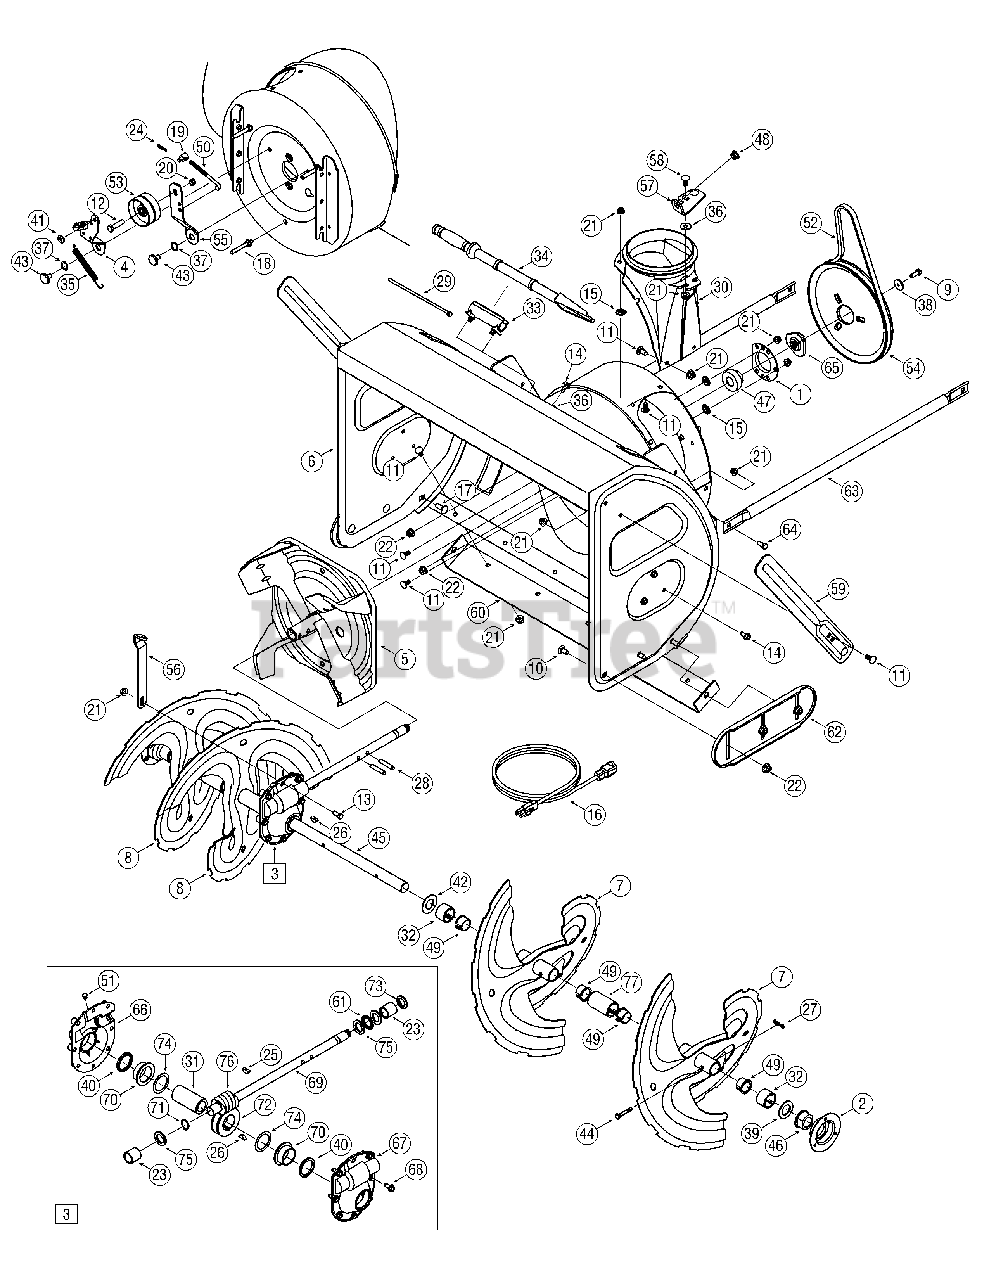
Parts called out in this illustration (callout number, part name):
1	Housing, Bearing
3	Gear Box Assembly, Auger
4	Bracket Assy, Auger Brake
9	Screw, 5/16-24 x .875
10	Bolt, Carriage 3/8-16 x .750
11	Screw, Carriage, 5/16-18 x .75
12	Screw, Hex Cap, 3/8-24 1.5
13	Screw, Hex Cap, 5/16-18 x 1.00
14	Screw, 5/16-18 x .750
15	Nut, Push
16	Extension Cord, 110V
17	Bolt, Carriage 3/8-16 x 1.0
18	Screw, 5/16-18 x .4300
19	Ferrule
20	Nut, Hex Lock, 3/8-24
21	Nut, Flange Lock, 5/16-18
22	Nut, Flange Lock, 3/8-16
23	Sleeve
24	Pin, Internal Cotter
25	Key, Hi Pro, 3/16 x 3/4
26	Key, Woodruff, 1/4 x 3/4
27	Pin, Bowtie Cotter
28	Pin, Spirol, 5/16 x 1.75
29	Tie, Cable
30	Adapter, Chute 6''
31	Shf, Gear Worm
32	Spacer, 1.0 x 1.5 x 1
33	Clip, Mounting
34	Tool, Cleanout
35	Spring, Extension
36	Washer, .349 x .879 x .063
37	Washer, .625 x .885 x.015
38	Washer, Flat, .34 x 1.50 x .150
39	Spacer, 1.004 x 1.375 x.25
40	Oil Seal
41	Washer, .344 x .75 x .12
42	Washer, 1.01 x 1.86 x.06
43	Screw, Shoulder, .625 x .17
44	Pin, Shear, .25 x 1.75
45	Axle, Sprial, 33''
46	Bearing, Flange w/ Flats
47	Bearing, Self Aligning
48	Bushing, Nylon
49	Bushing, Flange, 1.051 x 1.16
50	Rod, Auger Idler
52	V Belt, 1/2 x 44
53	Pulley, Flat Idler, 2.75 OD
54	Pulley, Auger Drive, 10.0
55	Bracket, Auger Idler
58	screw, Carriage, 5/16-18 x 1.00
61	Bearing, Thrust
65	Pulley Adapter, .75 Dia
66	Hsg Assy Auger RH (Inc. 40 & 70)
67	Hsg Assy Auger LH (Inc. 40 & 70)
68	Screw, LD, 5/16-18 x .750
69	Shf, Drive Auger
70	Flange Bearing
71	Ext, Ret Ring
72	Gear, Worm LH
73	Seal, Oil
74	Washer, Flat, 1.52 ID x 2.0 OD
75	Washer, Flat, .88 ID x .38 OD
76	Gear, Worm, Dbl Thread
77	Spacer
